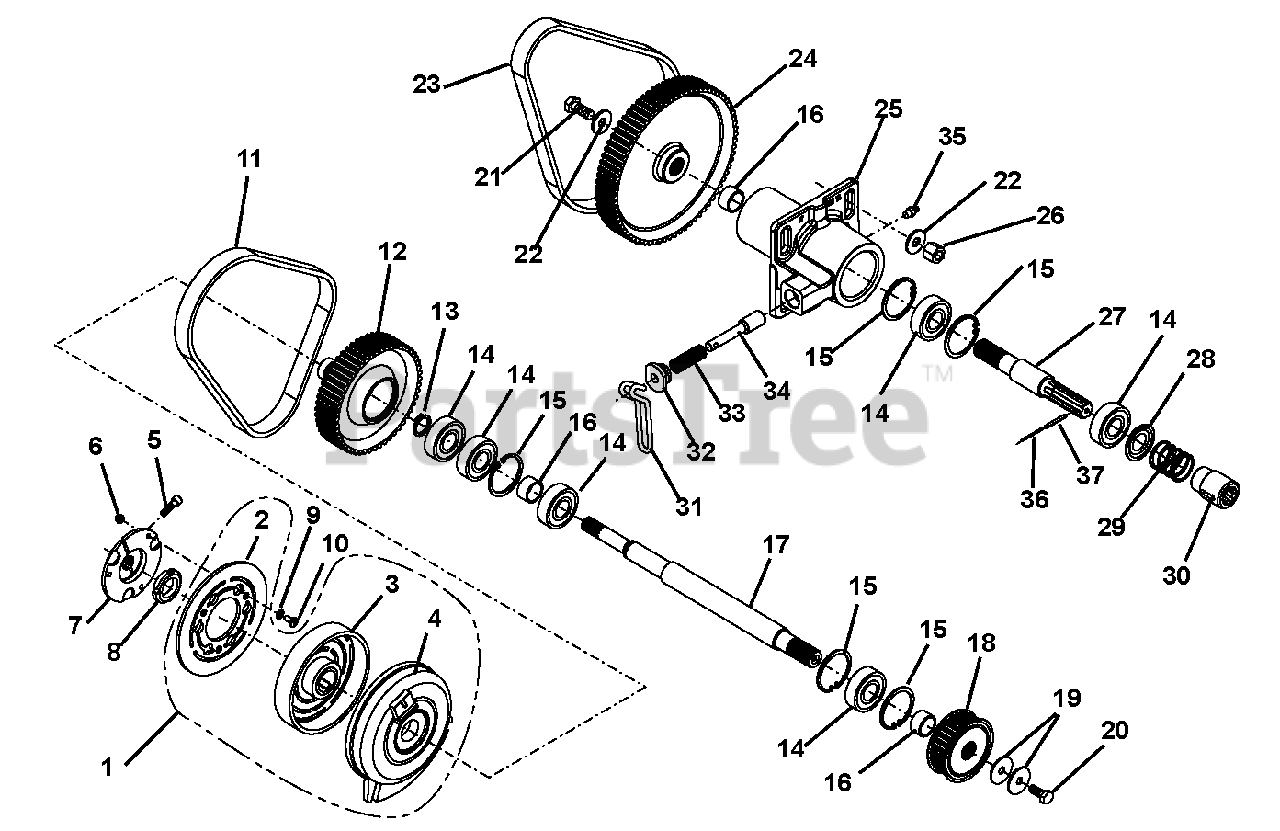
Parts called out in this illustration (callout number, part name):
1	Clutch, Magnet Positive (contains items 2 - 4)
2	Plate, Ancher
3	Rotor
4	Clutch Bellhousing
5	Screw, M6 x 20
6	Nut, Lock M5
8	Nut, Groove M24 x 1.5
9	Washer, 5.3 x 10 x 1
10	Screw, M5 x 12
11	Belt, Toothed
13	Circlip, D471 20 1.75
14	Ball Bearing, 6204 2RS /20 x 47 x 14
15	Circlip, D472 47 1.75
17	Clutch, Shaft
19	Washer, Friction
20	Bolt, Hex D933 M8 x 20
21	Bolt, Hex D933 M10 x 25
22	Washer, M10
23	Belt, Toothed L=800 B=20
25	P.T.O, Case
26	Nut, Hex D6330B M10 x 25
27	Power P.T.O.
28	NILOS, Ring N545 6204 ZAV
29	Spring, Pressure 2,25/29,75 x 47,90
30	Muff
32	Bolt, CF 3851
33	Spring, Pressure
34	Bolt, Lock
35	Lubricator
36	Dowel, Spring 2 x 40
37	Dowel, Spring 5 x 30
